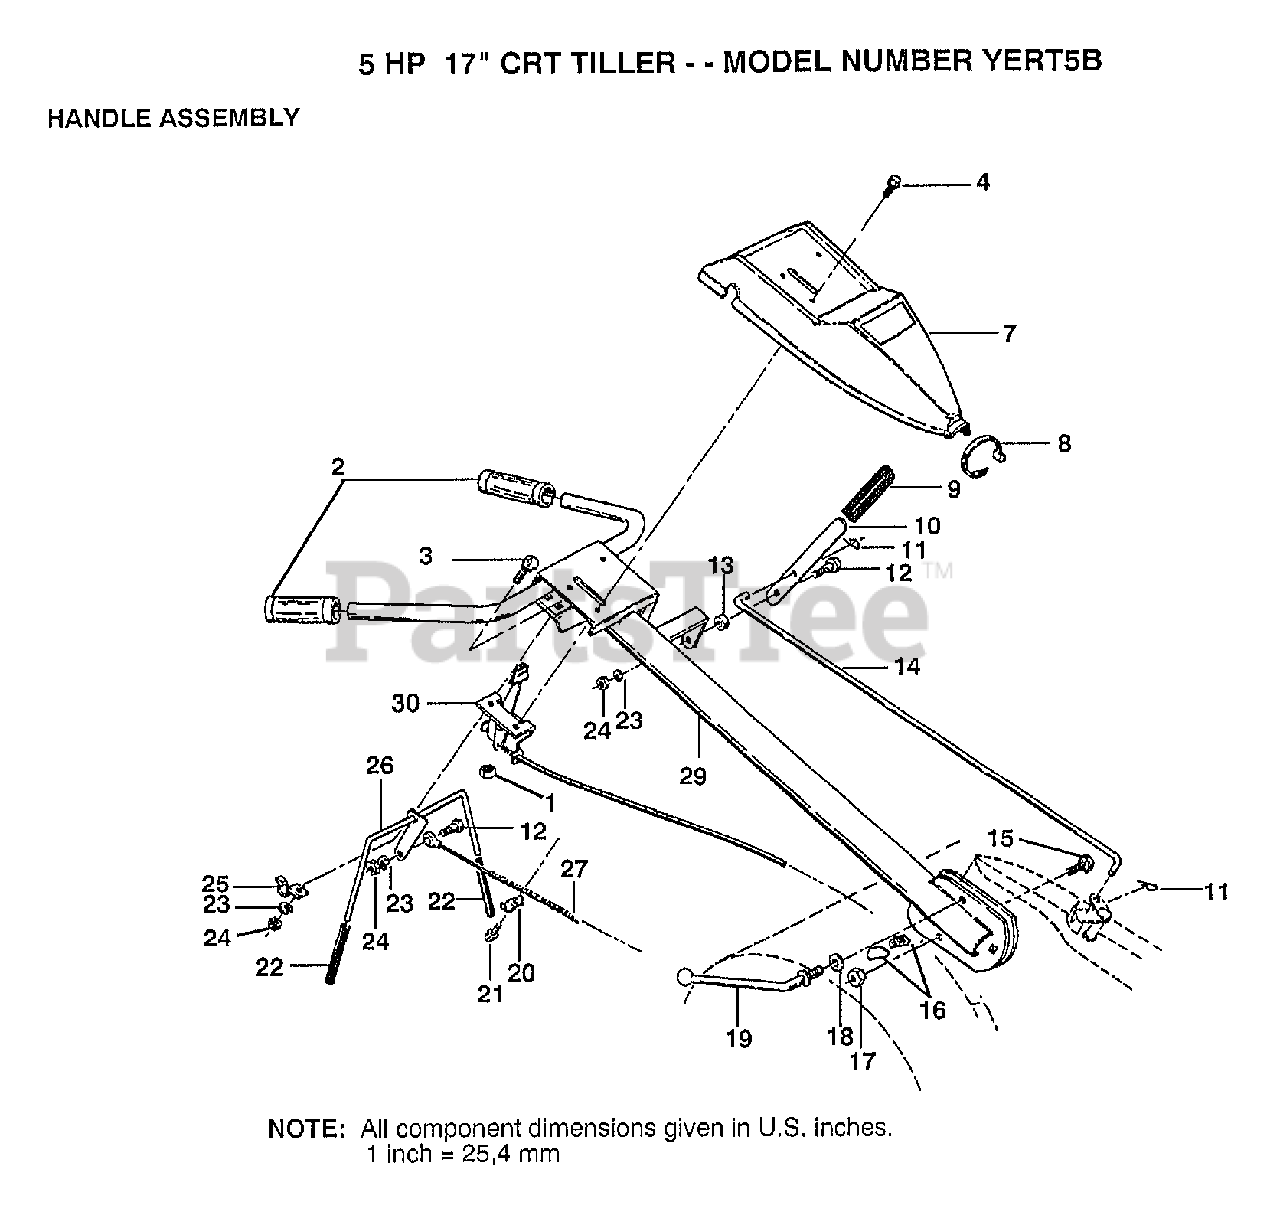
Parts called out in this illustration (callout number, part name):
3	BOLT
4	SCREW
7	"PANEL,CONT TI"
8	TIE CABLE CRT
9	GRIP T
10	SHIFT HANDLE CRT
11	RETAINER M
12	SHOULDER BOLT ST
13	GROMMET CRT
14	SHIFT ROD CRT
15	BOLT D
16	LOCK CRT
18	WASHER CRT
19	LEVER LOCK CRT
20	CONDIUT CLIP T
22	GRIP BAR CRT
23	LOCKWASHER
26	"ASSY CONTROL, BAR"
27	CABLE.CLUTCH.CRT
30	"CONT,THROTTLE"
